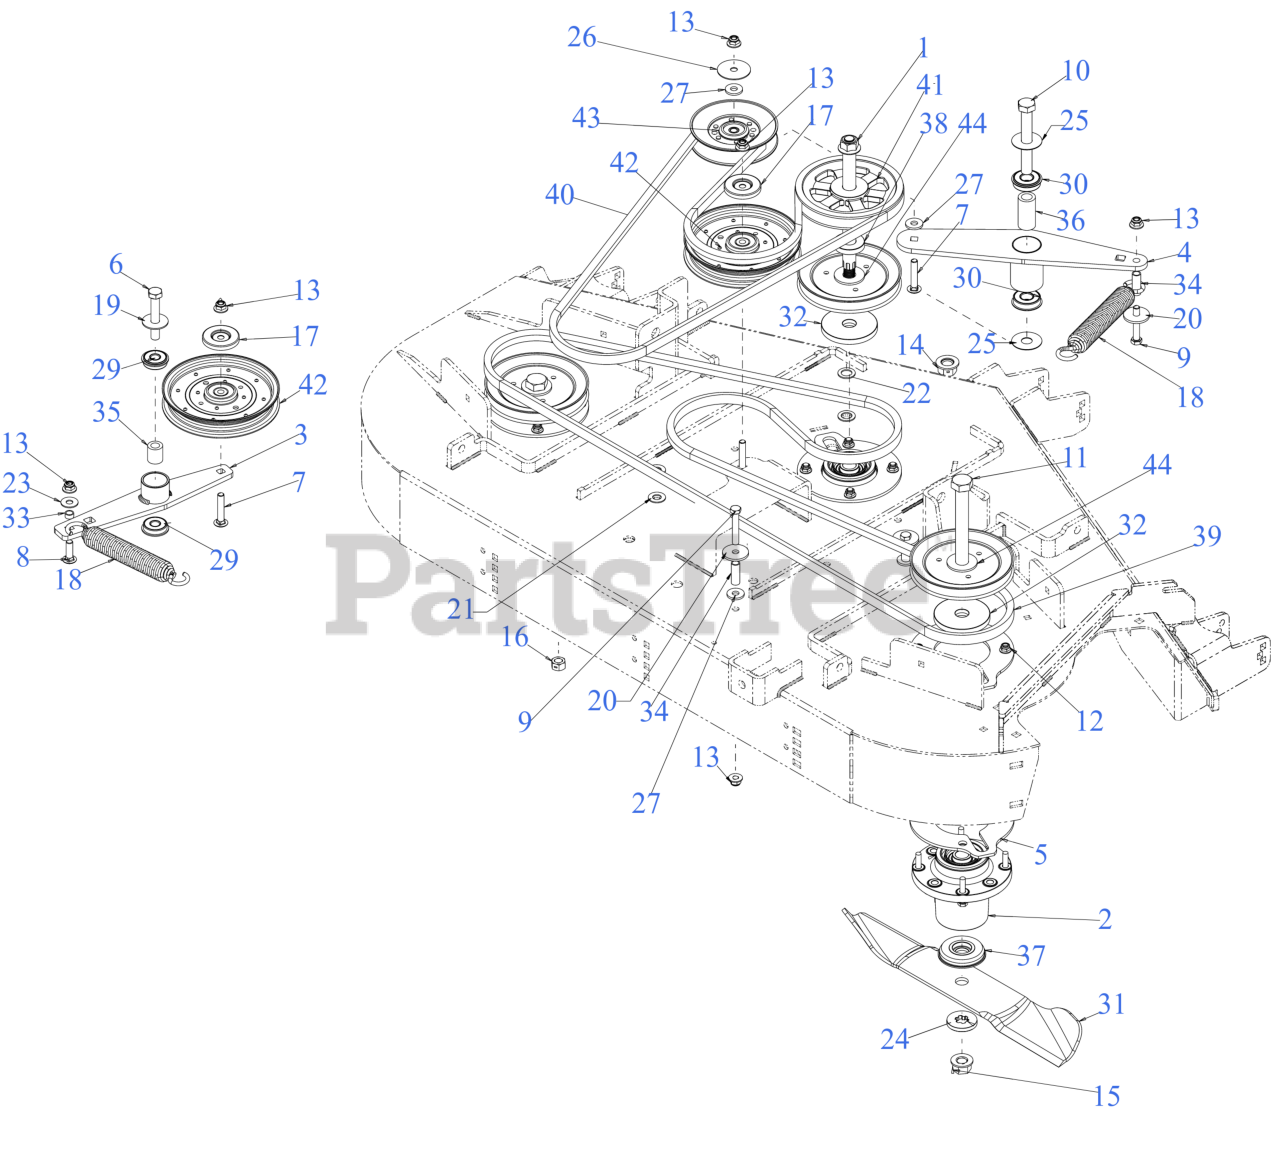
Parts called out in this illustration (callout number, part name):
1	SPINDLE SHAFT
2	SPINDLE ASSEMBLY
3	IDLER BRACKET
4	IDLER BRACKET
5	SPINDLE SUPPORT PLATE TOP & BOTTOM
6	SCREW-HEX 1/2-13 x 3.00
7	CARRIAGE BOLT 3/8-16 x 2
8	CARRIAGE BOLT 3/8-16 X1.25 GR5
9	HEX SCREW-3/8-16X2.5 GR5
9	SCREW 3/8-16 x 2.25 GR5
10	SCREW 5/8-18X4.5 GR5
11	SPINDLE SHAFT
12	FLANGE LOCK NUT 5/16-18
15	FLANGE NUT - 5/8-18 GDE 8
16	HEX NUT CTR LK 1/2-13
17	PULLEY CAP
18	SPRING 1.25" DIA x 8.5" LONG
19	WASHER .51 x 1.5 x .07
20	FLAT WASHER .390x1.500x.134
20	FLAT WASHER .406X1.500X.105
21	FLAT WASHER .510 x .995
22	FLAT WASHER
23	WASHER-.395 x 1.0 x .62
24	FLAT WASHER - SPECIAL
25	FLAT WASHER 0.635xX1.755x0.110
25	THRUST WASHER .635x1.750x0.055
26	HUB CAP WASHER .406 x 1.92 x .060
27	FLAT WASHER .406ID X1.0 OD
29	ROLLER BEARING .5X1.37X.44
30	BALL BEARING W/RET
31	19" BLADE
32	DECK SPINDLE SPACER
33	SPACER
34	SPACER
35	SPACER 0.51 x 0.88 x 1.00
36	SPACER 0.63 x 1.00 x 2.01
37	SPACER 0.790 x 2.75 x 0.486
38	SPACER
39	BELT-B SECTION 119.45"
40	BELT SEC B x 90.30
41	PULLEY-6.96 OD x .750 ID
42	IDLER PULLEY
43	IDLER PULLEY 5.06 OD
44	V-PULLEY 6.426"
